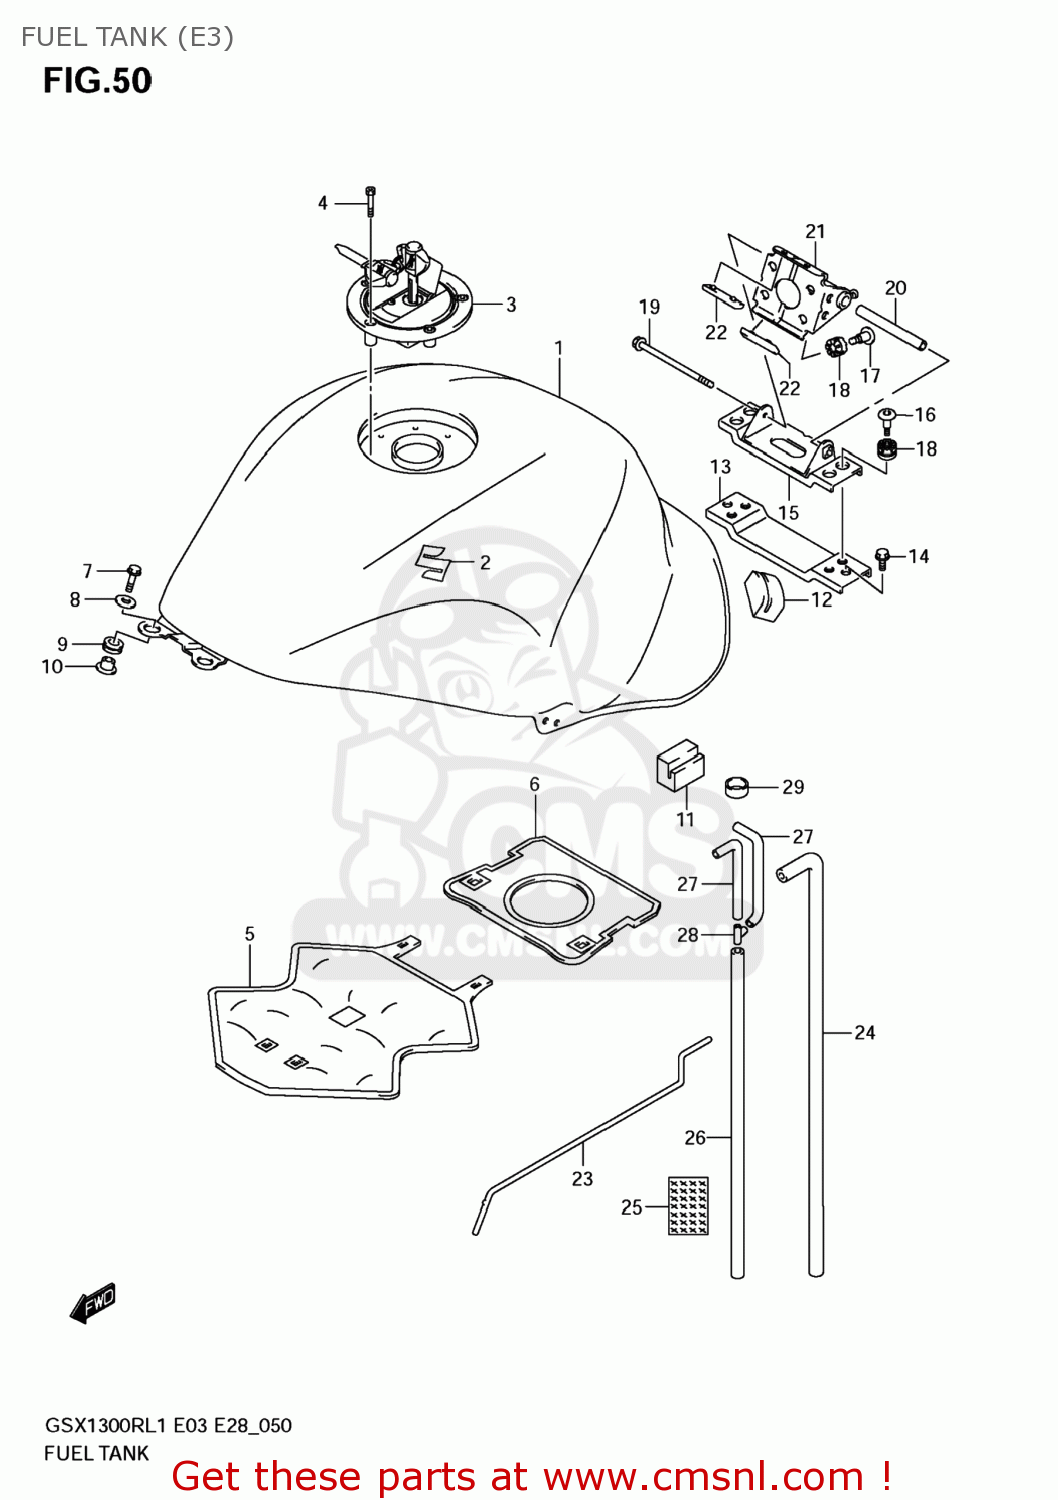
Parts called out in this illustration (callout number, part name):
1	TANK ASSY,FUEL
2	EMBLEM,S
3	CAP SET,FUEL TANK
4	BOLT(5X20)
5	SHIELD,FUEL TANK HEAT NO.1
6	SHIELD,FUEL TANK HEAT NO.2
7	SCREW(6X25)
8	WASHER(6.5X22X1.6)
9	CUSHION,FUEL TANK FR
10	SPACER,FUEL TANK FR
11	CUSHION,FUEL TANK SIDE
12	CUSHION,FUEL TANK RR
13	BRACKET,FUEL TANK RR NO.3
14	BOLT
15	BRACKET,FUEL TANK RR NO.2
16	SCREW(6X22)
17	SCREW(6X22)
18	CUSHION
19	BOLT
20	SPACER,FUEL TANK RR
21	STEUN.BENZ.TANK
22	CUSHION,SEAT FR
23	STAY,FUEL TANK
24	HOSE,FUEL TANK DRAIN
25	SHIELD,DRAIN HOSE HEAT
26	HOSE,FUEL TANK BREATHER
27	HOSE,TANK BREATHER NO.2
28	3 WAY
29	HOSE(12X16X600)
